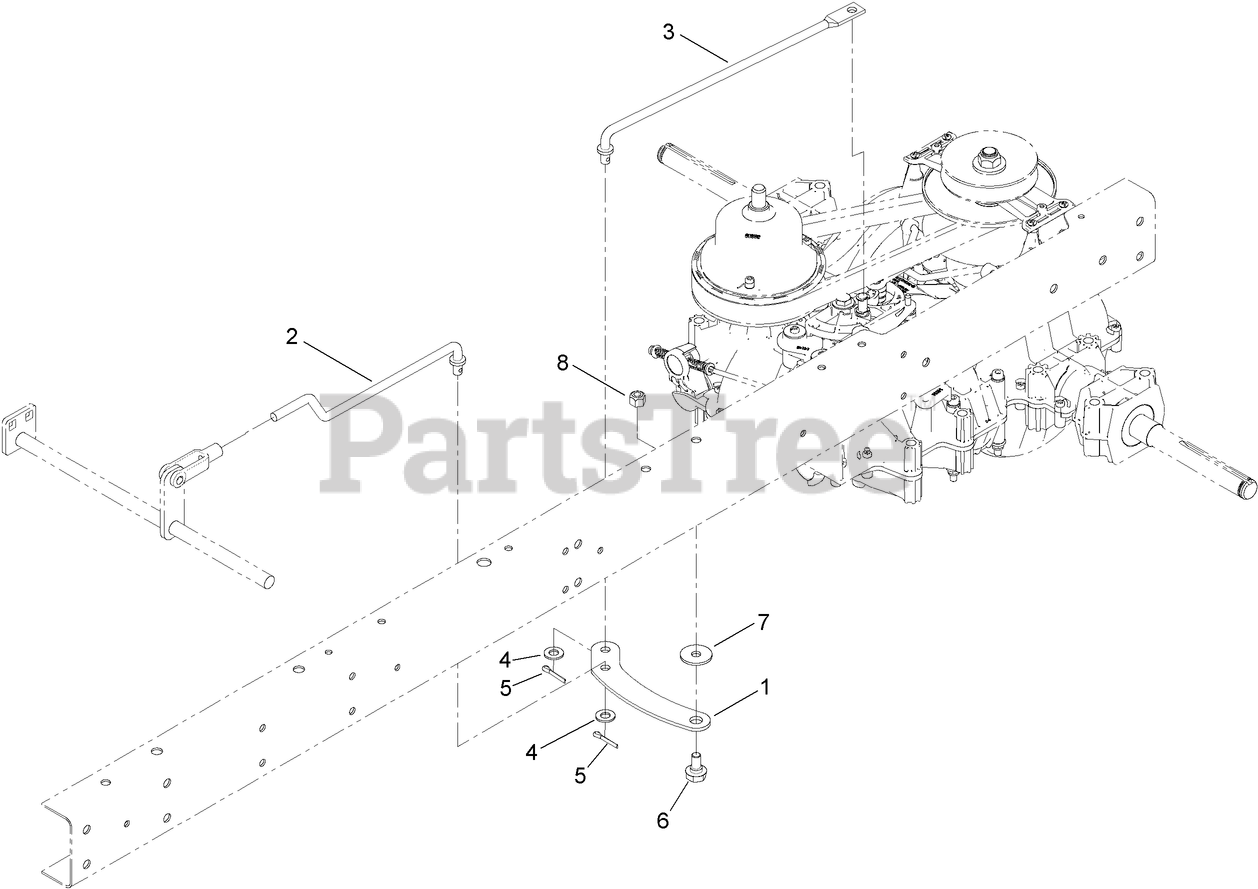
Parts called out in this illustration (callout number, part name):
1	BRACKET-TRACTION, LINK ARM
2	ROD-MOTION CONTROL, FRONT
3	ROD-MOTION CONTROL, REAR
4	WASHER-PLAIN
5	PIN-COTTER
6	BOLT-SHOULDER
7	WASHER-PIVOT
8	NUT-LOCK, NI
